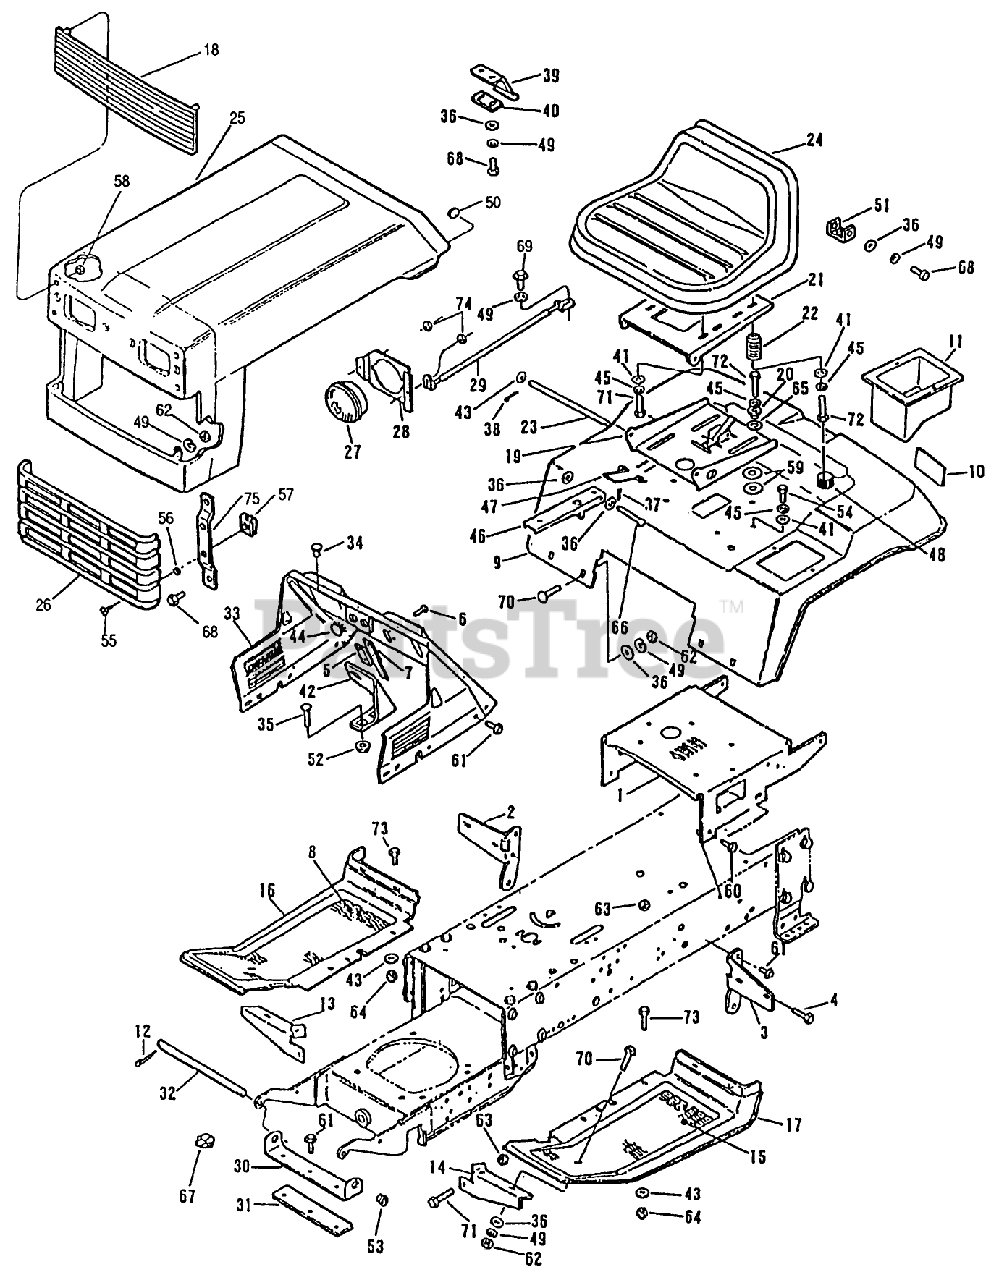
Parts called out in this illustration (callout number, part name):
2	SUPPORT - RH
4	SCREW
9	SEAT PAN AY.
10	REFLECTOR
19	SEAT SUPPORT AY
21	PIVOT AY - SEAT *B
23	PIN
25	HOOD GRILLE WLDMT *G
26	INSERT - GRILLE
33	INST PANEL & DECAL AY *B
43	WASHER
46	LATCH - SEAT PAN *B
48	CAP-PROTECTOR
53	BEARING-NYLINER
55	FASTENER-1/4 TURN
59	WASHER-PLASTIC
62	NUT
63	NUT
64	NUT-LOCKING
66	PIN
67	CLIP-RETAINER, WIRE
68	SCREW-HH
69	SCREW
71	SCREW - HEX
72	SCREW
